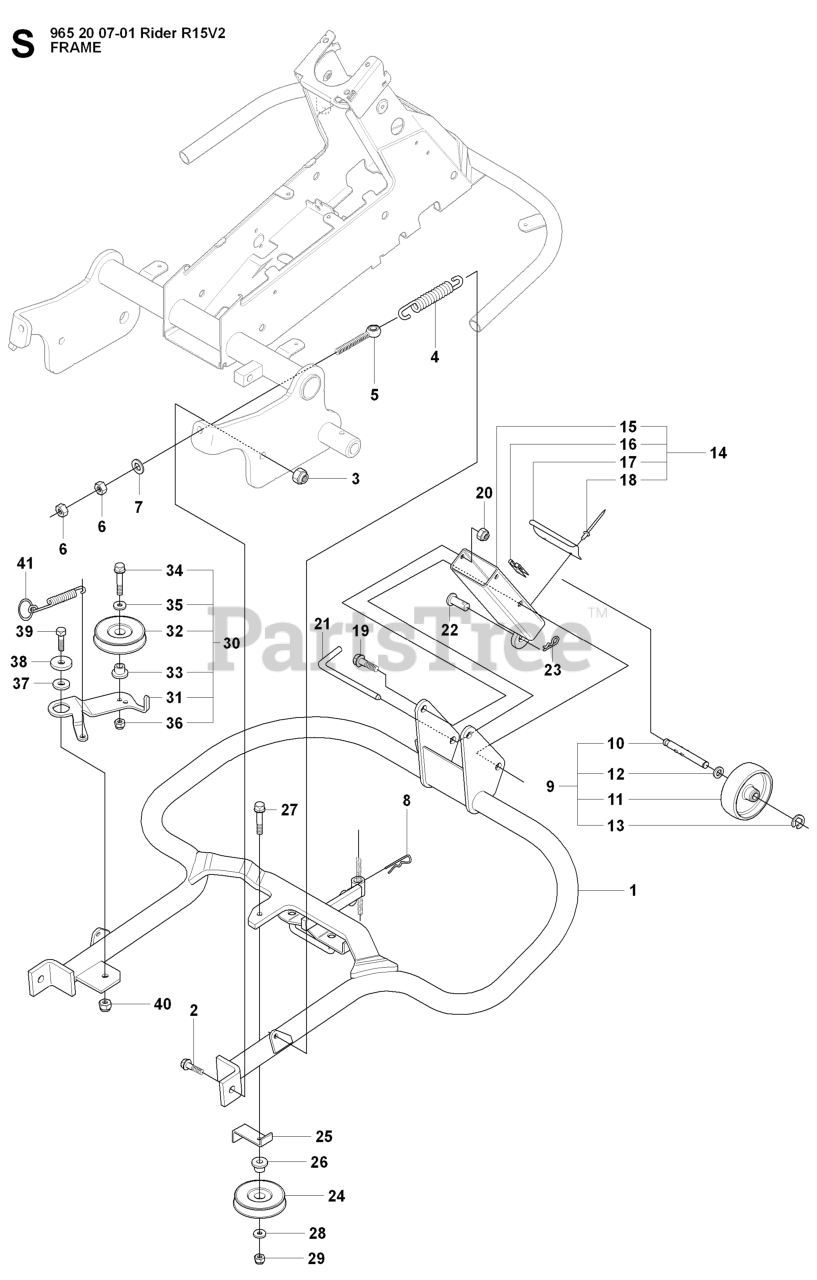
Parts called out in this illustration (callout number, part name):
6	NUT
7	WASHER
9	WHEEL ASSY
13	RETAINING RING
20	LOCKNUT M8
29	LOCKNUT M8
30	BELT TENSIONER ASSY
36	LOCKNUT M8
40	NUT
